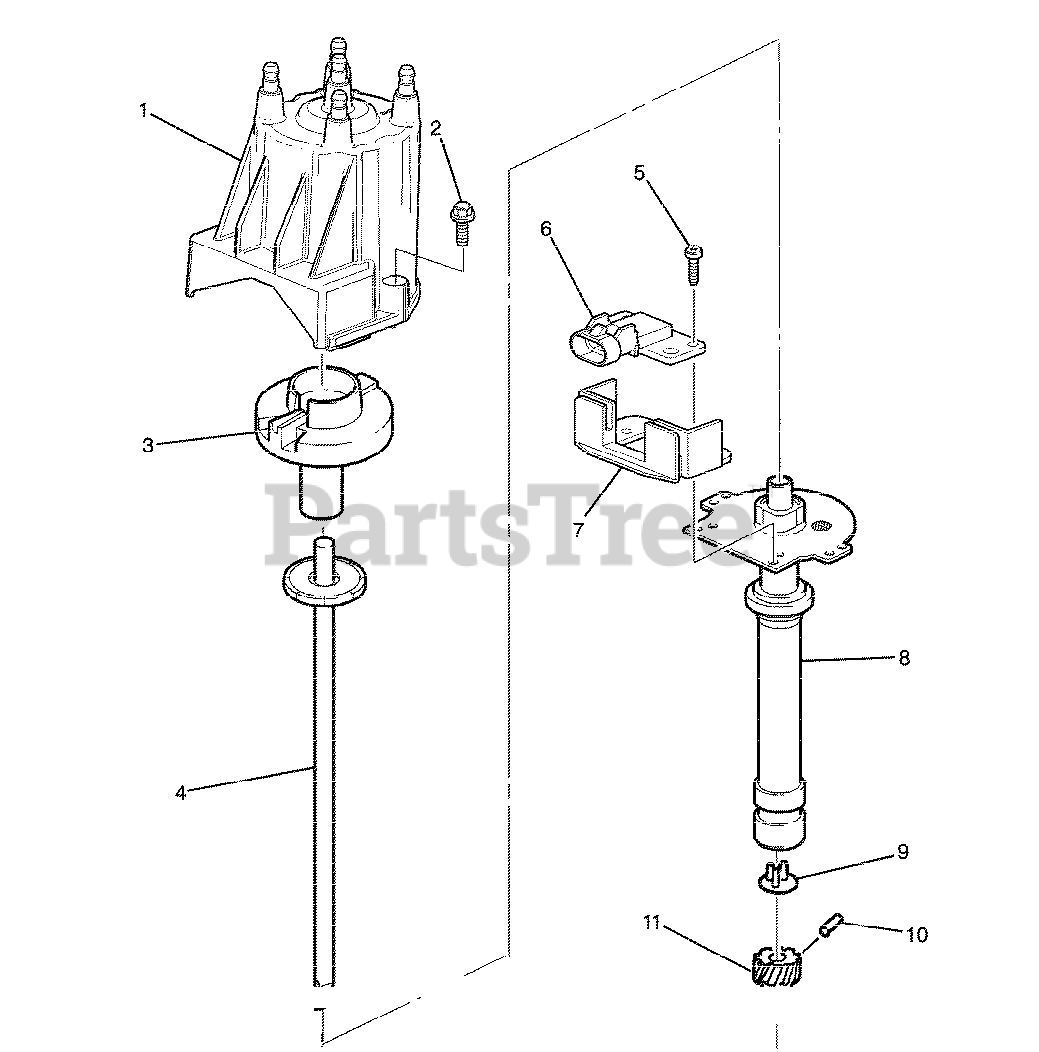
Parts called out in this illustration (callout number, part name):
2	* BOLT
4	* SHAFT
5	* BOLT
7	* BRACKET
8	* HOUSING
9	* WASHER
10	* PIN
11	* GEAR
